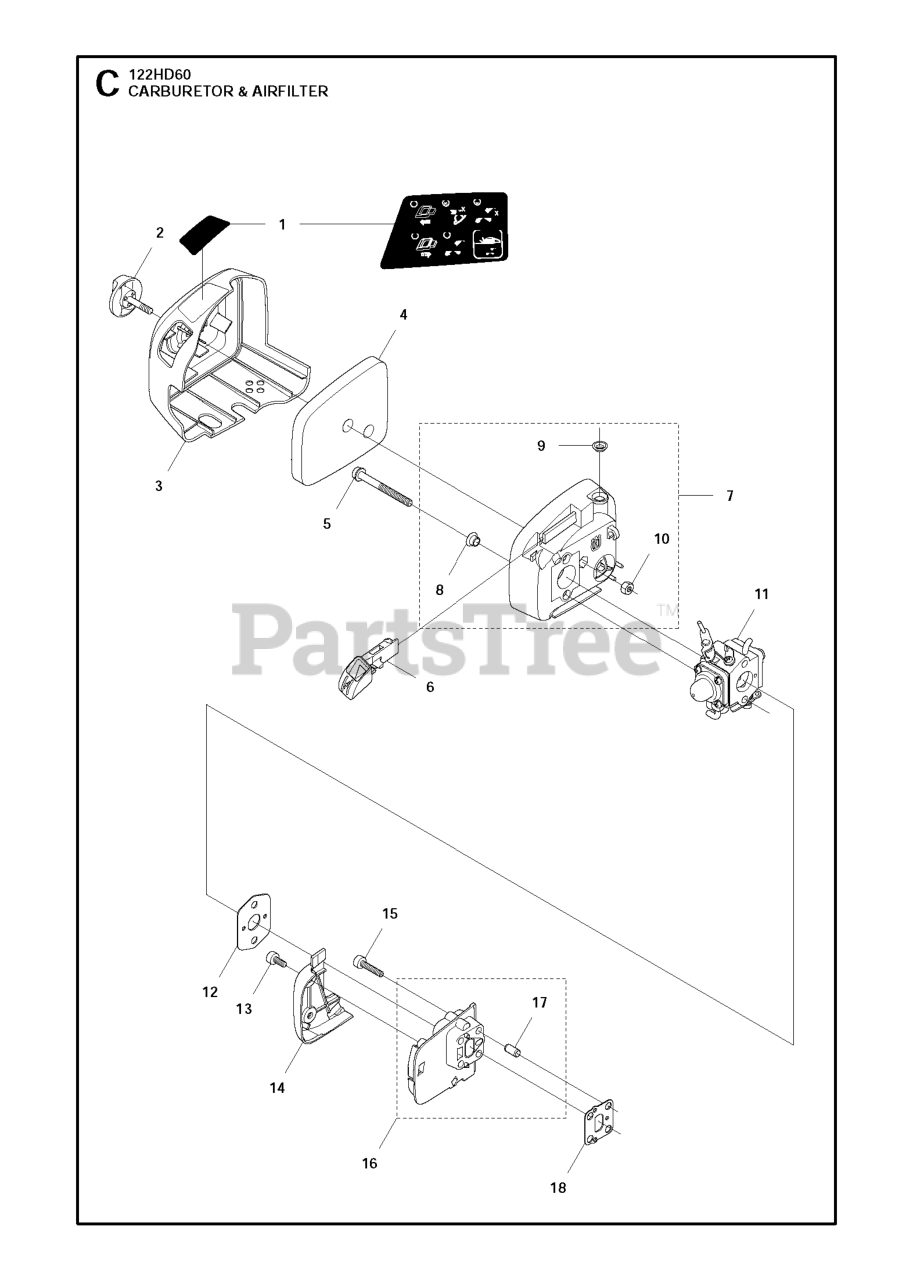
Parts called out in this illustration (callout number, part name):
3	AIR FILTER COVER
4	AIR FILTER
7	FILTER HOLDER ASSY.
8	RIVET TUBULAR
9	RIVET TUBULAR
11	CARBURETOR ASSY.
17	TUBULAR RIVET
